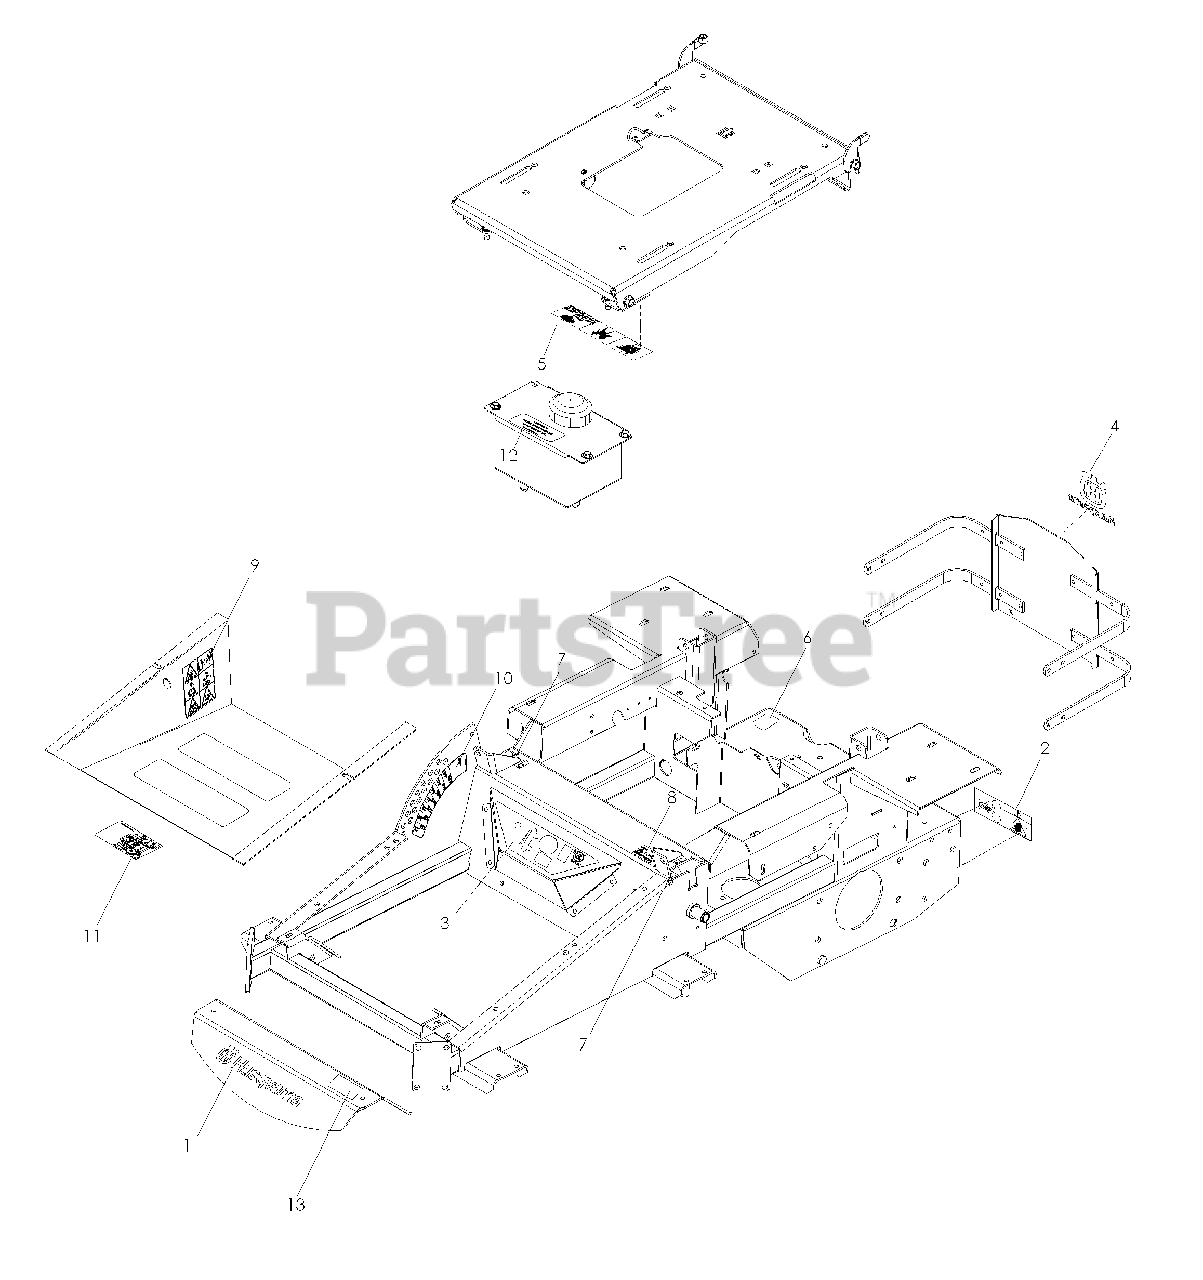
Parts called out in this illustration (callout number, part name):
1	DECAL, HUSQ. 12" BLUE
2	DECAL, DANGER
3	DECAL, CONSOLE
4	DECAL, HUSQ. SILVER
5	DECAL, BATTERY WARNING
6	DECAL, PROP 65
7	DECAL, MOTION CONTROL
8	DECAL, TRACKING
9	DECAL, WARNING
10	DECAL, HEIGHT
11	DECAL, SERVICE
12	DECAL, OIL TANK
13	DECAL, iZ21
13	DECAL, iZ25
